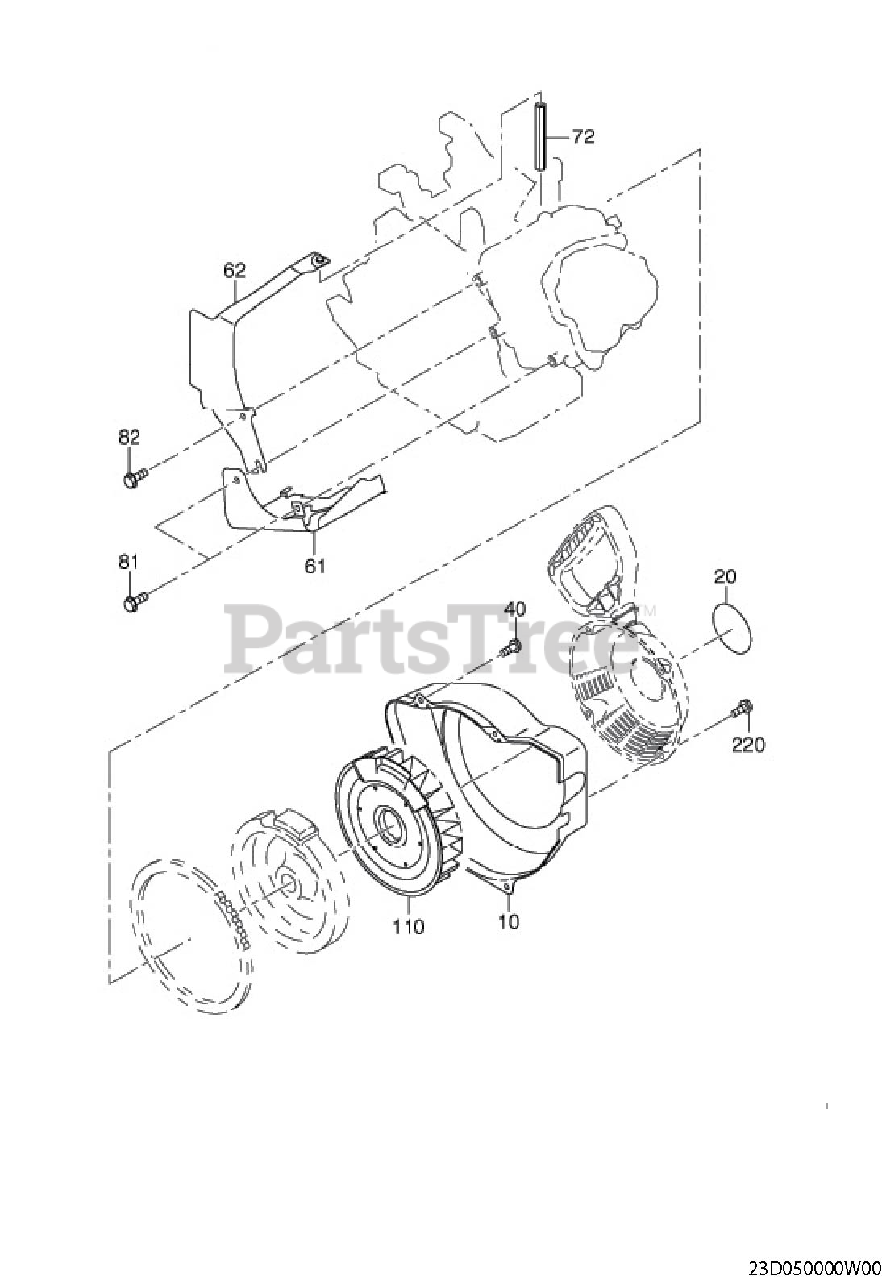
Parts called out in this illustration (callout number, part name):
10	BLOWER HOUSING CP
20	LABEL(TRADE MARK)
40	FLANGE BOLT
61	BAFFLE 2(HEAD)
62	BAFFLE 3 CP
72	HEXAGONAL POST
81	FLANGE BOLT
82	FLANGE BOLT
110	COOLING BLOWER
220	FLANGE BOLT
